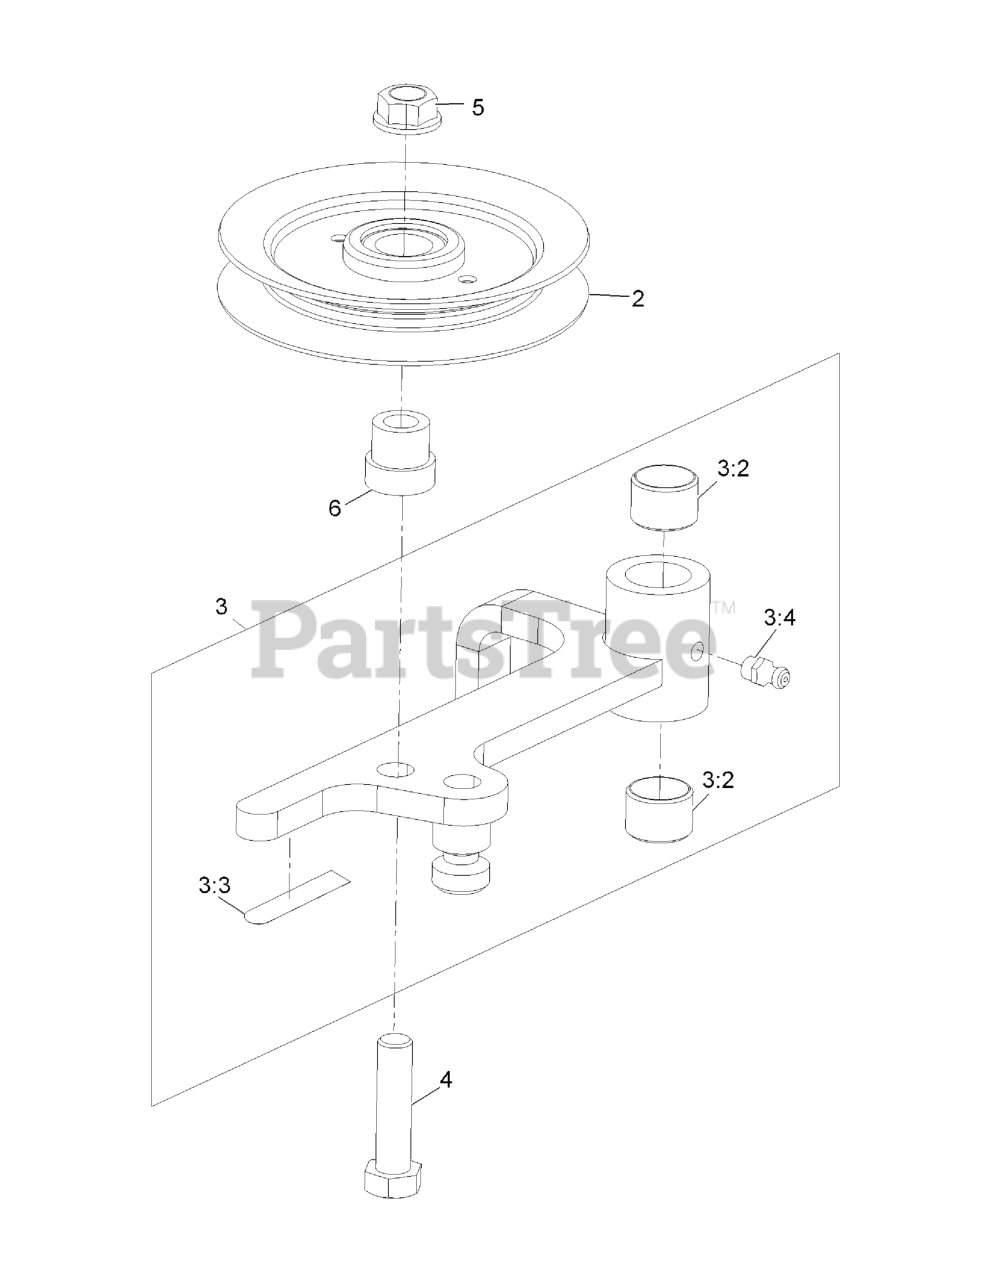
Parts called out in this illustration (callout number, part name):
3	ASM, IDLER ARM - SERVICE ONLY
3:2	BUSHING
3:3	DECAL-WARNING
3:4	FITTING-GREASE
4	SCREW-HH
5	NUT-HHF, WHIZ
6	HUB,SPACER
